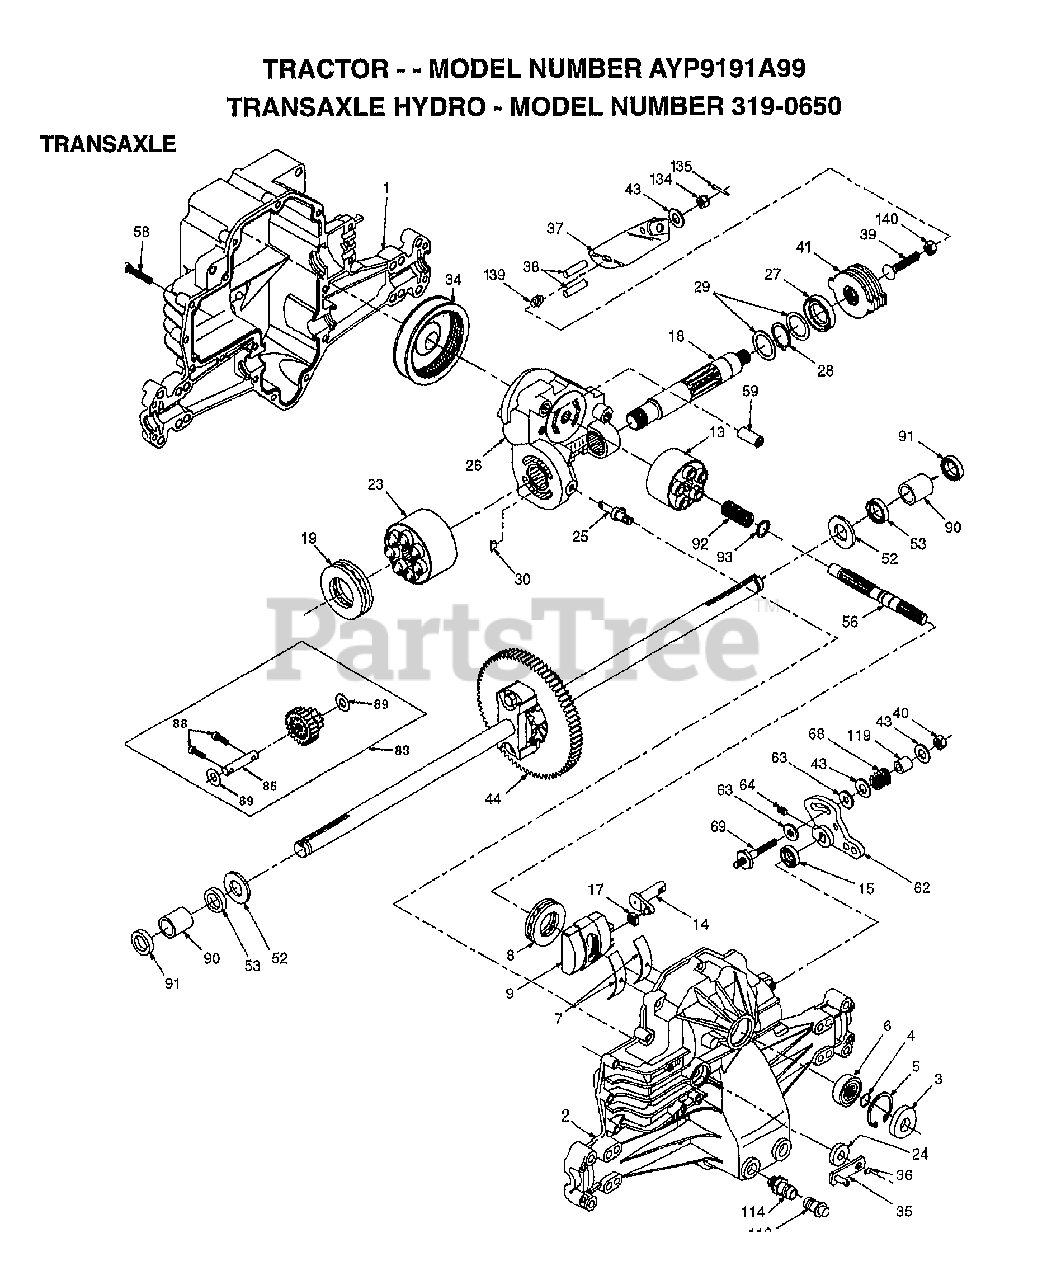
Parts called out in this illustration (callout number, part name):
1	HOUSING.L.50074RM
2	HOUSING.UP.70125
3	SEAL.9008000-0128
4	RING.RET.2003016.
5	RING.RET.2003052.
6	BEARING.(50552)42X68X16
7	CRADLE- 2003023.
8	BEARING.THU.50551
9	SWASHPLT.2003087.
13	BLOCK.CLYN.70079.
14	ARM.TRUN.2003005.
15	SEAL.9008000-0126
17	GUIDE.2000015.
18	SHAFT.MOTOR.50449
19	BEARING.THU.50552
23	BLOCK.CYLIN.70082
24	SEAL.LIP.45074
25	ACTUATOR.2003555
26	KIT.CEN.SEC.70250
27	SEAL.LIP.45075
28	RING RETAIN 50007
29	WASHER.44872
30	PLATE.BYP.2003554
34	ELEMENT.OIL.44964
35	ARM.BYPASS.50270
36	RING.RETAIN.44870
37	ARM.ACTUAT.23710
38	PIN.ACTUAT.44891
39	BOLT.50316
40	NUT.LOCK.HX.50317
41	KIT.BRAKE.70135
43	WASHER HYD 44130
44	DIFFRENTIAL.70226
52	WASHER.HYD.44875
53	SEAL.HYDRO.45076
56	SHAFT.INPUT.50005
58	BOLT.1/4-20.44876
59	PIN.HYDRO.50002
62	ARM.CONTROL.50254
63	PUCK.DAMPER.50281
64	SCREW.SET.50018.
68	SPRING.HYD.50277
69	STUD.5/16-24.DANA
83	JACKSHAFT/PINION GEAR.70132
85	PIN.SHAFT 50559
88	SCREW.CAP.50154.
89	WASHER.HYD.50132
90	BEARING.SLV.50118
91	SEAL.WIPER.50941
92	SPRING.2003014.
93	WASHER.2003017
113	CAP.VENT.70109
114	O-RING.ASM.70110
119	SPACER.HYD.50278
134	NUT.CAS.HYD.44142
135	PIN.COT.HYD.44101
139	SPRING.COMP.50431
140	NUT.HEX.50269
